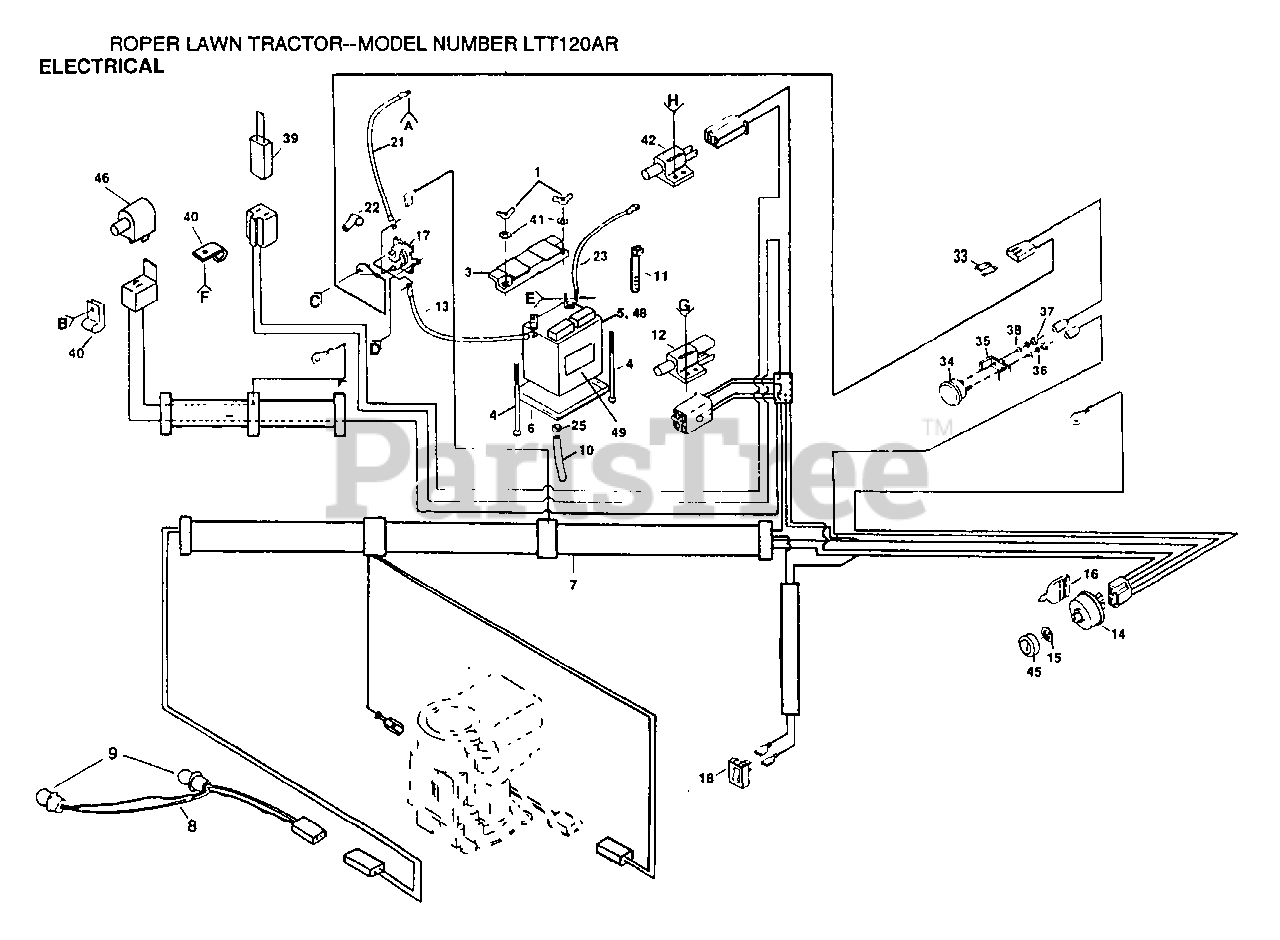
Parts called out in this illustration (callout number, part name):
4	BOLT
6	"TRAY T, BATTERY"
7	IGNITION HARNES
8	HARNESS T
11	WIRE TIE
12	SWITCH INTERLOCKT
13	CABLE-BATTERY T
18	SWITCH LT
21	CABLE LT
23	CABLE T
25	HOSE CLAMP T
33	FUSE HYT
34	AMMETER T
38	WASHER
40	CLIPT
41	LOCKWASHER GT
42	SWITCH-INTER. GT
46	SWITCH SEAT
48	"CAP,BATTERY "
49	DECAL
